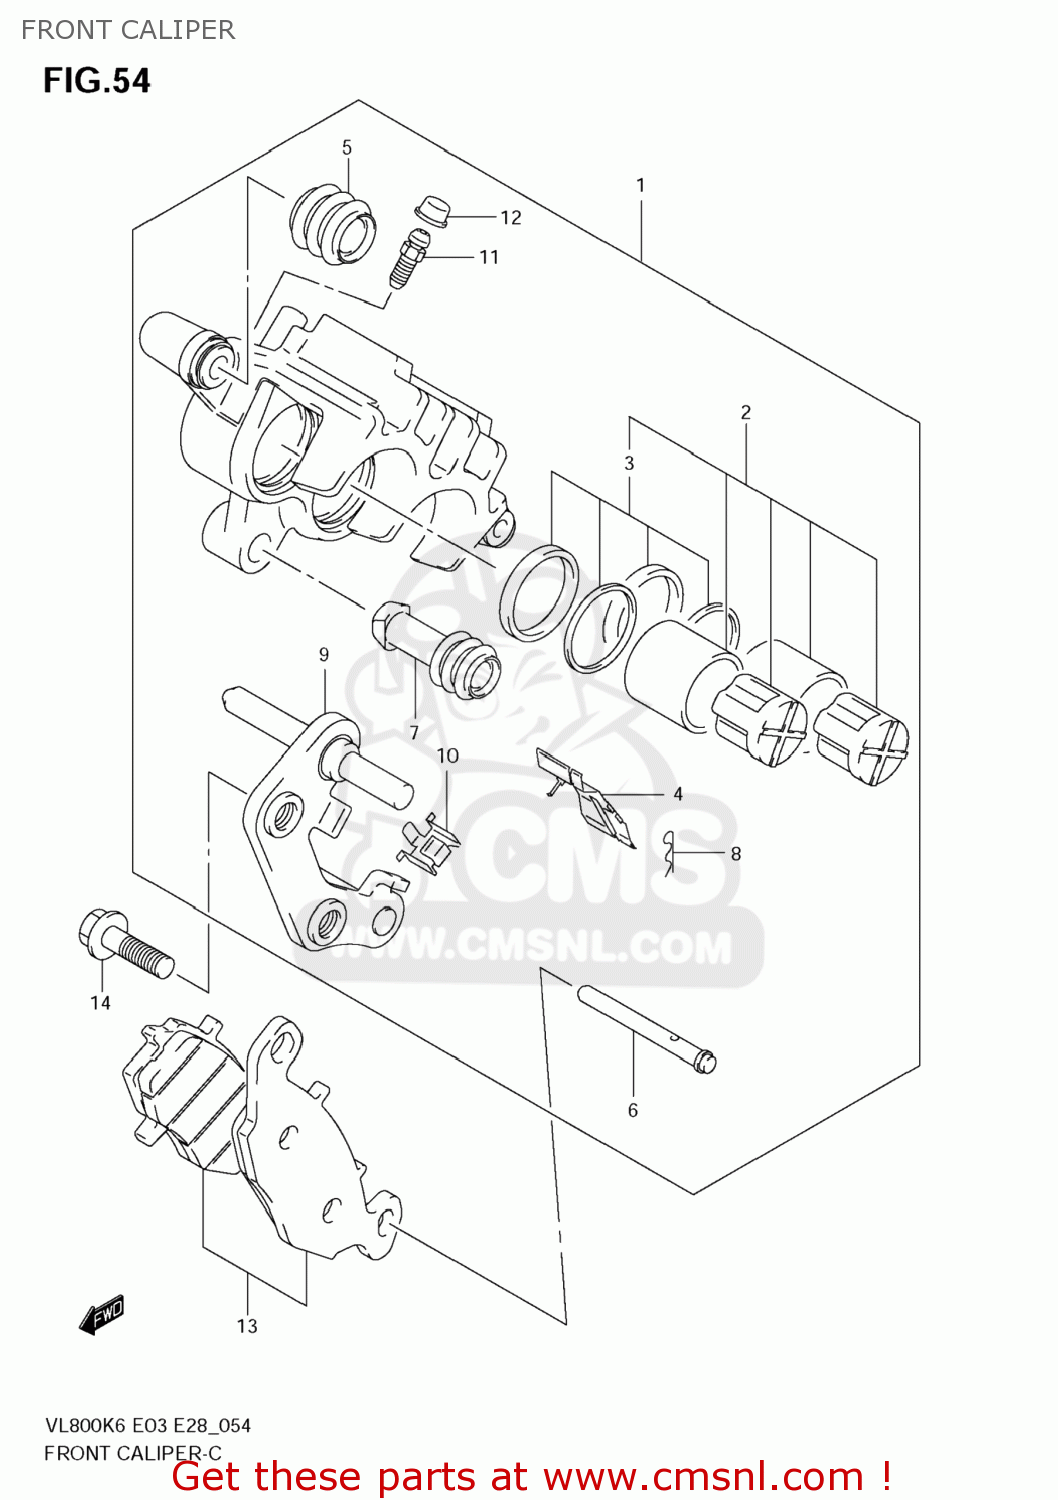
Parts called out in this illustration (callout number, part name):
1	CALIPER ASSY,FR
2	PISTON SET
3	SEAL SET,PISTON
4	SPRING,PAD,R
5	BOOT,AXLE
6	PIN,PAD
7	INSULATOR,AXLE
8	CLIP,PAD PIN
9	CARRIER,CALIPER,R
10	GUIDE,PAD
11	BLEEDER
12	CAP,BLEEDER PLUG
13	PAD SET (NAS)
14	BOLT(10X30)
